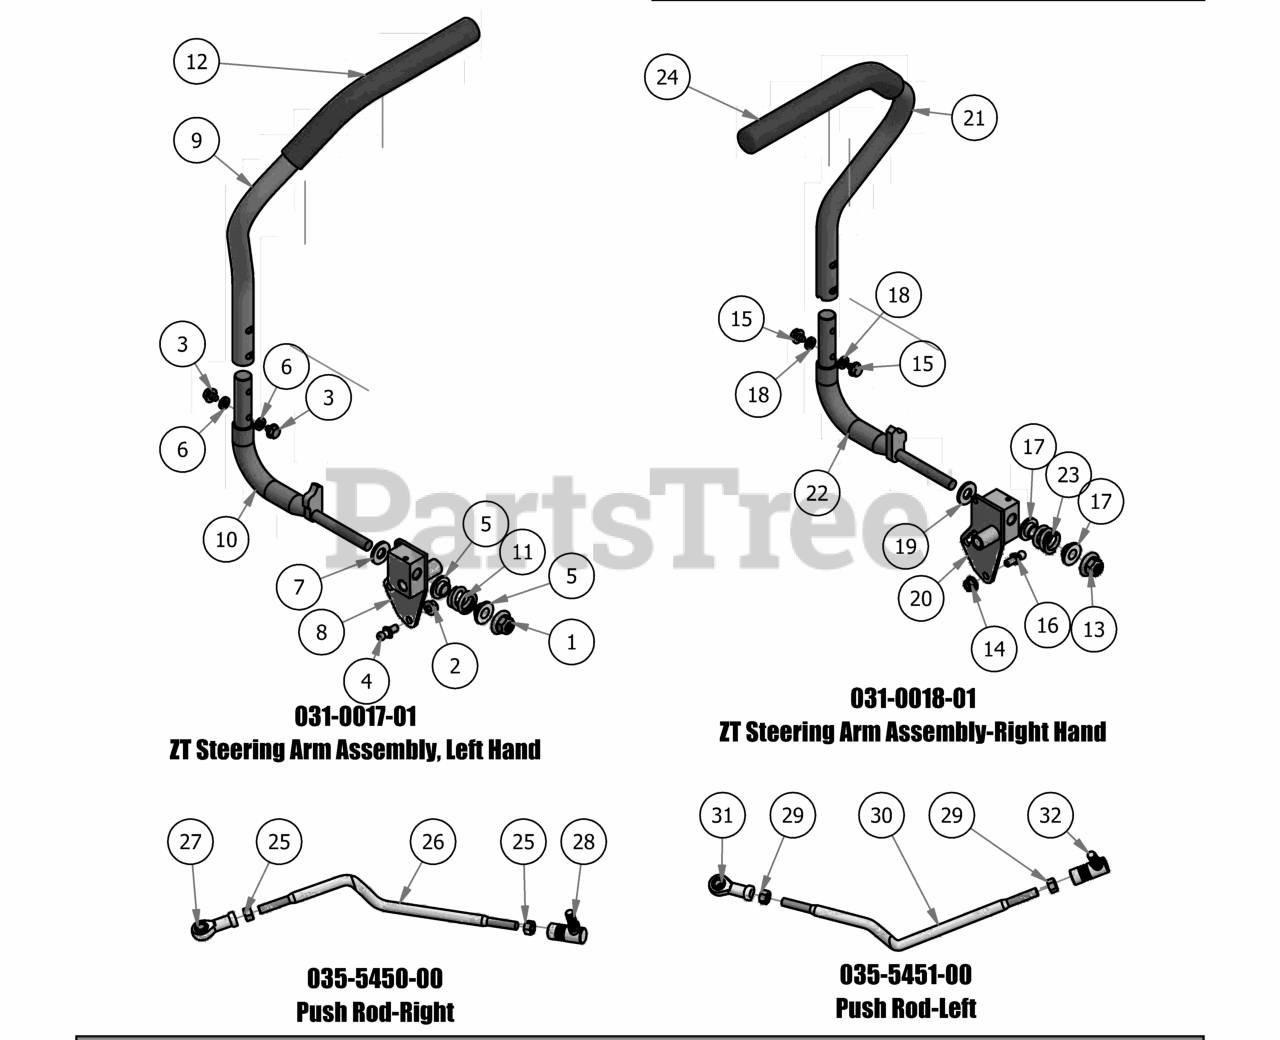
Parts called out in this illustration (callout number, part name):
1	1/2-13 Nylon Flange Nut
2	5/16" Flange Nut
3	5/16-18 1/2 HWH Bolt-Steering
4	10mm Damper Ball Stud-Steering
5	.515 ID Nylon Shoulder Washer
6	5/16" Lock Washer
7	.505 Nylon Spacer
8	2017 Drive Lever Level Housing LH
9	ZT Direction Steering Arm (Left)
10	Steering Arm Elbow - Left
11	Drive Lever Spring
12	Rubber Grip
13	1/2-13 Nylon Flange Nut
14	5/16" Flange Nut
15	5/16-18 1/2 HWH Bolt-Steering
16	10mm Damper Ball Stud-Steering
17	.515 ID Nylon Shoulder Washer
18	5/16" Lock Washer
19	.505 Nylon Spacer
20	2017 Drive Lever Housing RH
21	ZT Direction Steering Arm (Right)
22	Steering Arm Elbow - Right
23	Drive Lever Spring
24	Rubber Grip
25	3/8" Fine Threaded Jam Nut
26	Push Rod - Right
27	Spherical Rod End - Outlaw
28	Quick Release Ball Joint
29	3/8" Fine Threaded Jam Nut
30	Push Rod - Left
31	Spherical Rod End - Outlaw
32	Quick Release Ball Joint
